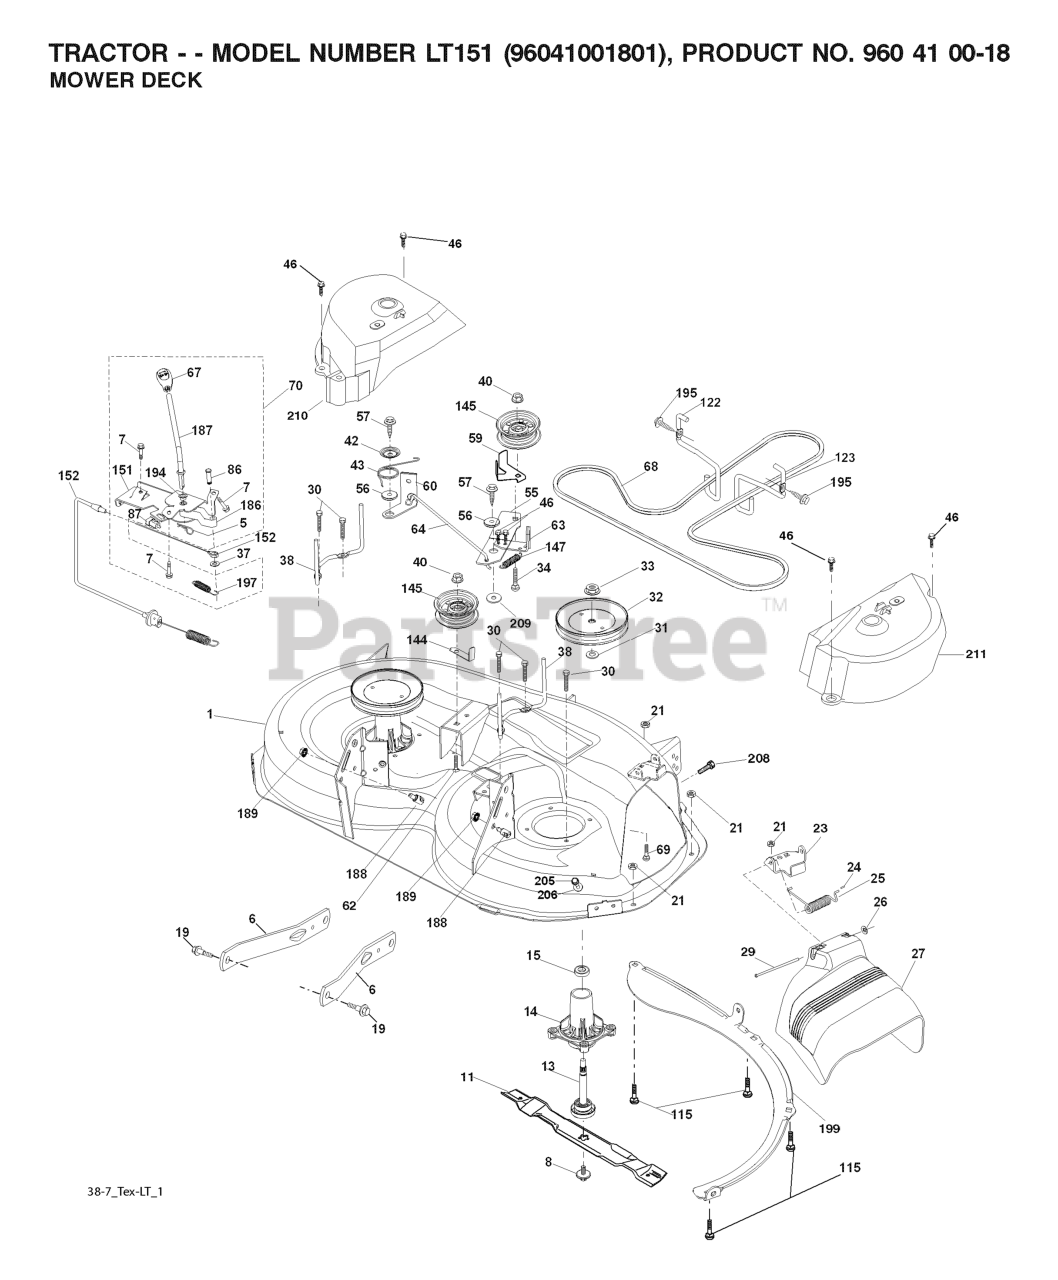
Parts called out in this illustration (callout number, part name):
1	HOUSING
5	RETAINER-SPRNG RB
6	ARM.SUSPENSION.MOWER.R
7	SCREW
8	BOLT.WASHER.ASM.7/16-2
11	BLADE 38" PREMIUM
19	BOLT.SHOULDER
21	LOCKNUT
23	BRKT.DEFLECTOR.38"2005+
24	CAP-SLEEVE LT
25	SPRING.TORSION.DEFLECT
26	NUT PUSH M
27	SHIELD.DEFLECTOR.MWR.38-7/97CM
29	ROD.HINGE
30	SCREW, WASHER HEAD
31	WASHER.SPACER.MANDREL
32	PULLEY.MANDREL.5.0.PD.38"
33	NUT.FLANGE.LOCK.TOP
34	BOLT.3/8-16X1.50
36	PULLEY.IDLER.48"PRIMARY
37	WASHER
38	KEEPER BELT LH MANDREL
40	NUT LOCK FLG 3/8-16 UNC
42	SPRING.TORSION.BRAKE
43	SRPING.TORSION.RETAINE
46	SCREW.1/4-20X5/8
56	SPACER.RETAINER
57	SCREW 3/8-16X1
59	GUARD, BELT
60	ARM BRAKE MOWER RH 38"
62	BOLT.3/8-16X1.50
63	RP ARM.BRAKE.MOWER.38"LH.TEX
64	LINK BRAKE
67	HANDLE.CLUTCH.CABLE.LT
69	BOLT
70	CLUTCH.ASM.MANUAL.LT.PRED
86	PIN ATTACHMENT CABLE
87	SWITCH.INTRLCK.CLUTCH.
122	KEEPER BELT ENGINE LH
123	KEEPER BELT RH
144	KEEPER, BELT IDLER
147	SPRING RETURN
151	BRACKET.CLUTCH CBL.PRED LT
152	CLUTCH CABLE
186	ARM ACTUATOR
187	LEVER.CONTROL.CL.CABLE.PRED LT
188	STUD.FASTNER.W/ANTI-ROTATE
189	NUT LOCK HEX FLANGE 5/16-18
194	BEARING.CONTROL.LEVER.CLUTCH
195	SCREW, 3/8-16X3/4
197	SPRING.PLUNGER.ACTUATOR
199	BAFFLE.VORTEX.FRONT.38"
209	WASHER 12/32X2X10GA
